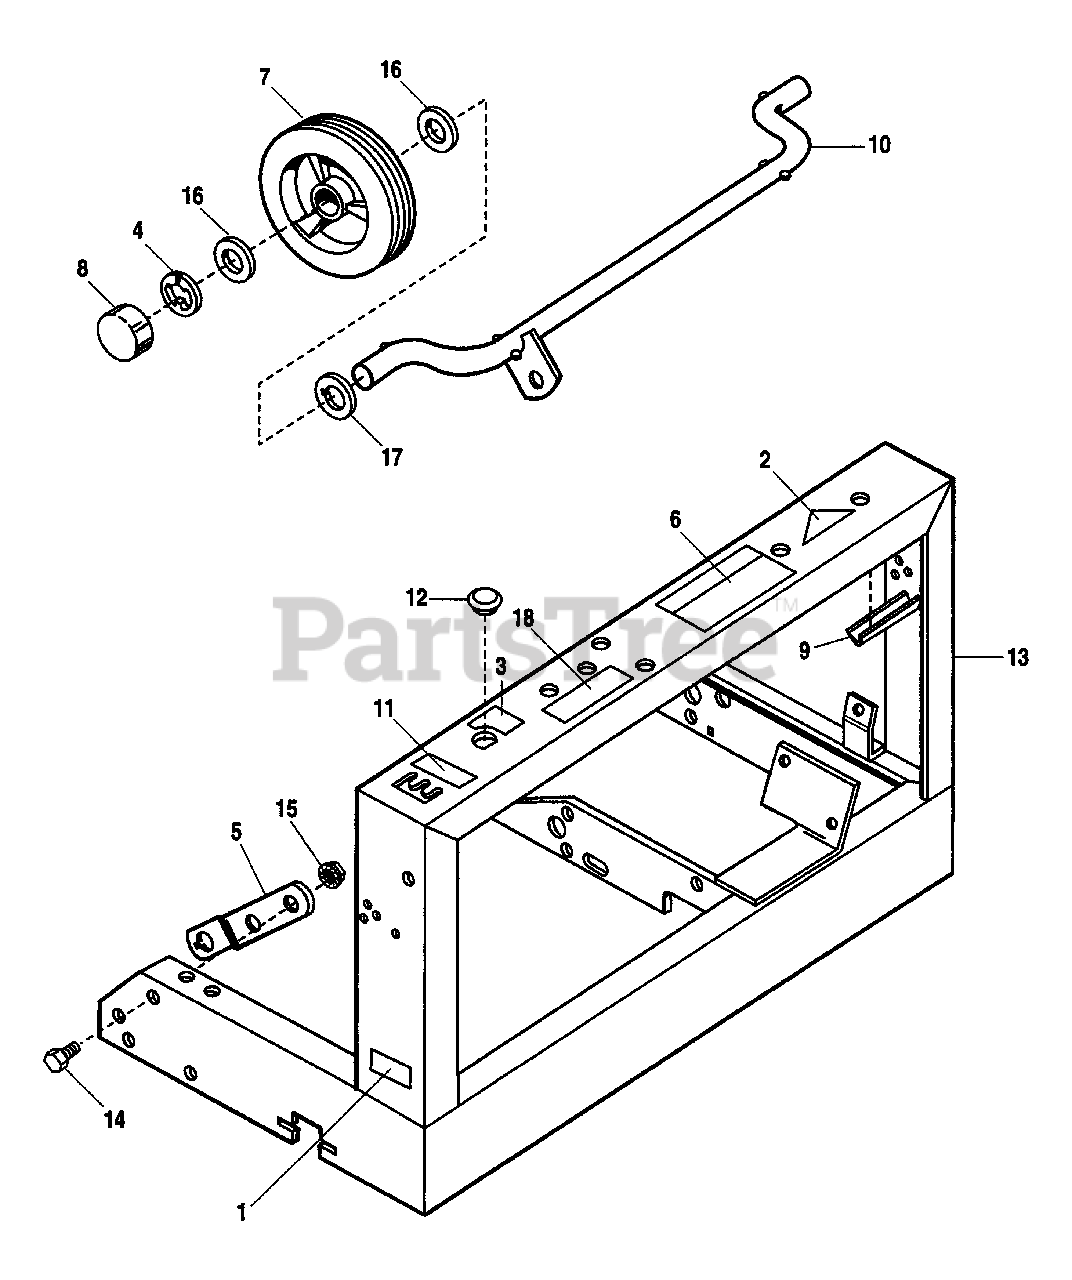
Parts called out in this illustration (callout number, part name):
1	I.D. PLATE
2	DECAL, OPEI
3	DECAL, Ignition (Electric start models only)
4	KLIP RING, External (for 5/8" Shaft)
5	BRACKET Axle
6	DECAL, Operating Instructions
7	WHEEL, Front, 8 x 1-3/4
8	HUBCAP, Front Wheels
9	EDGE PROTECTOR
10	AXLE ASSY., Front
11	DECAL, Nozzle height
12	PLUG, Hole, Double "D" (Manual start models only)
13	FRAME ASSY.
14	CAPSCREW, Hex Hd., 5/16-18 x 3/4
15	NUT, Serrated, Flange Lock, 5/16-18
16	WASHER, 5/8
17	WASHER, Keyhole
18	DECAL, Danger
